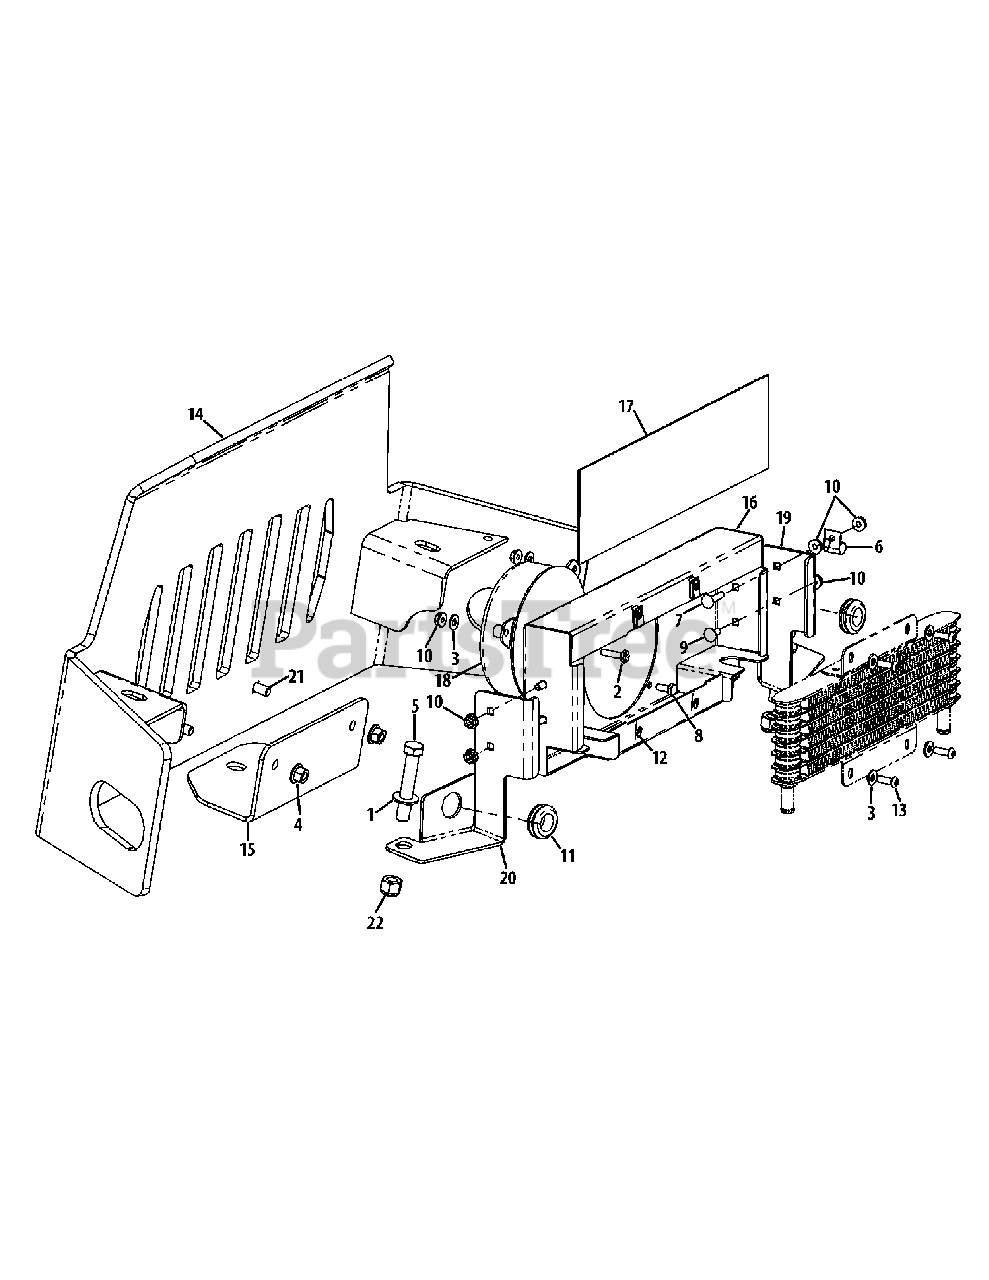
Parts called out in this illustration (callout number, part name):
1	Washer, 1/2
2	Capscrew, 1/4-20 x 1.00
3	Washer, 1/4
4	Flange Lock Nut, 3/8-16
5	HHCS, 1/2-13, 3.00
6	Clamp, 1/2
7	Carriage Bolt, 1/4-20 x 1.00
8	Hex Screw, 1/4-20 x .620
9	Carriage Screw, 1/4-20 x .62
10	Nut, 1/4-20, Hex Flange Lock
11	Grommet, .75 ID
12	U-Nut, 1/4-20
13	Capscrew, 1/4-20 x .750
14	Bumper Assembly
15	Hitch Bracket
16	Heat Exchanger Assembly
17	Heat Exchanger Screen
19	Cooler Mounting Bracket, LH
20	Cooler Mounting Bracket, RH
21	Carriage Bolt, 3/8-16 x 1.00
22	Hex Nut, 1/2-13, Insert Lock
